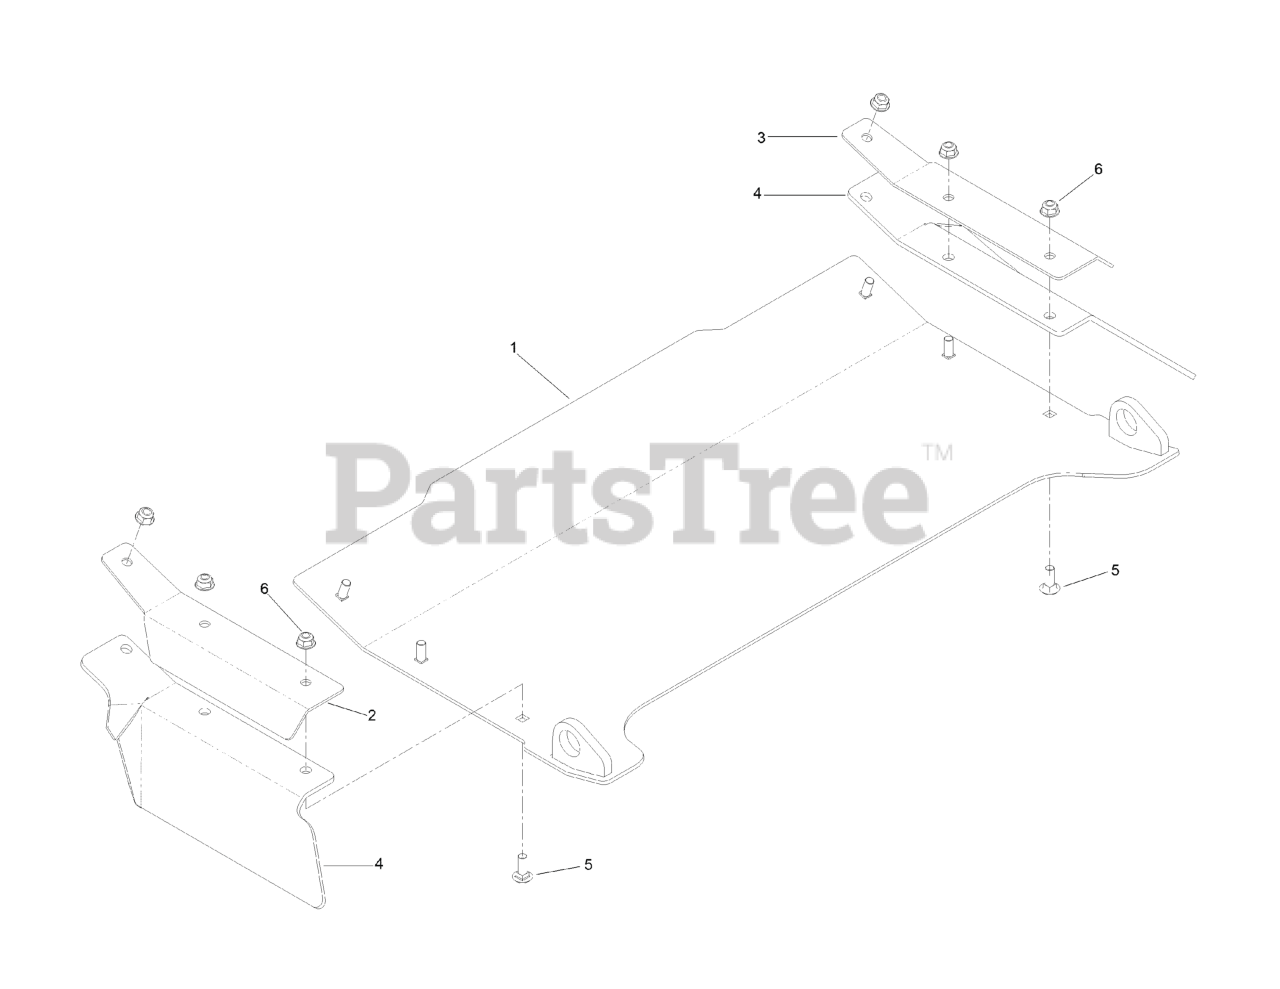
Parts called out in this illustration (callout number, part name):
1	DISCHARGE TUNNEL ASM
2	BRACKET-FLAP, LH
3	BRACKET-FLAP, RH
4	FLAP-RUBBER
5	SCREW-CARR
6	NUT-HF, NI
